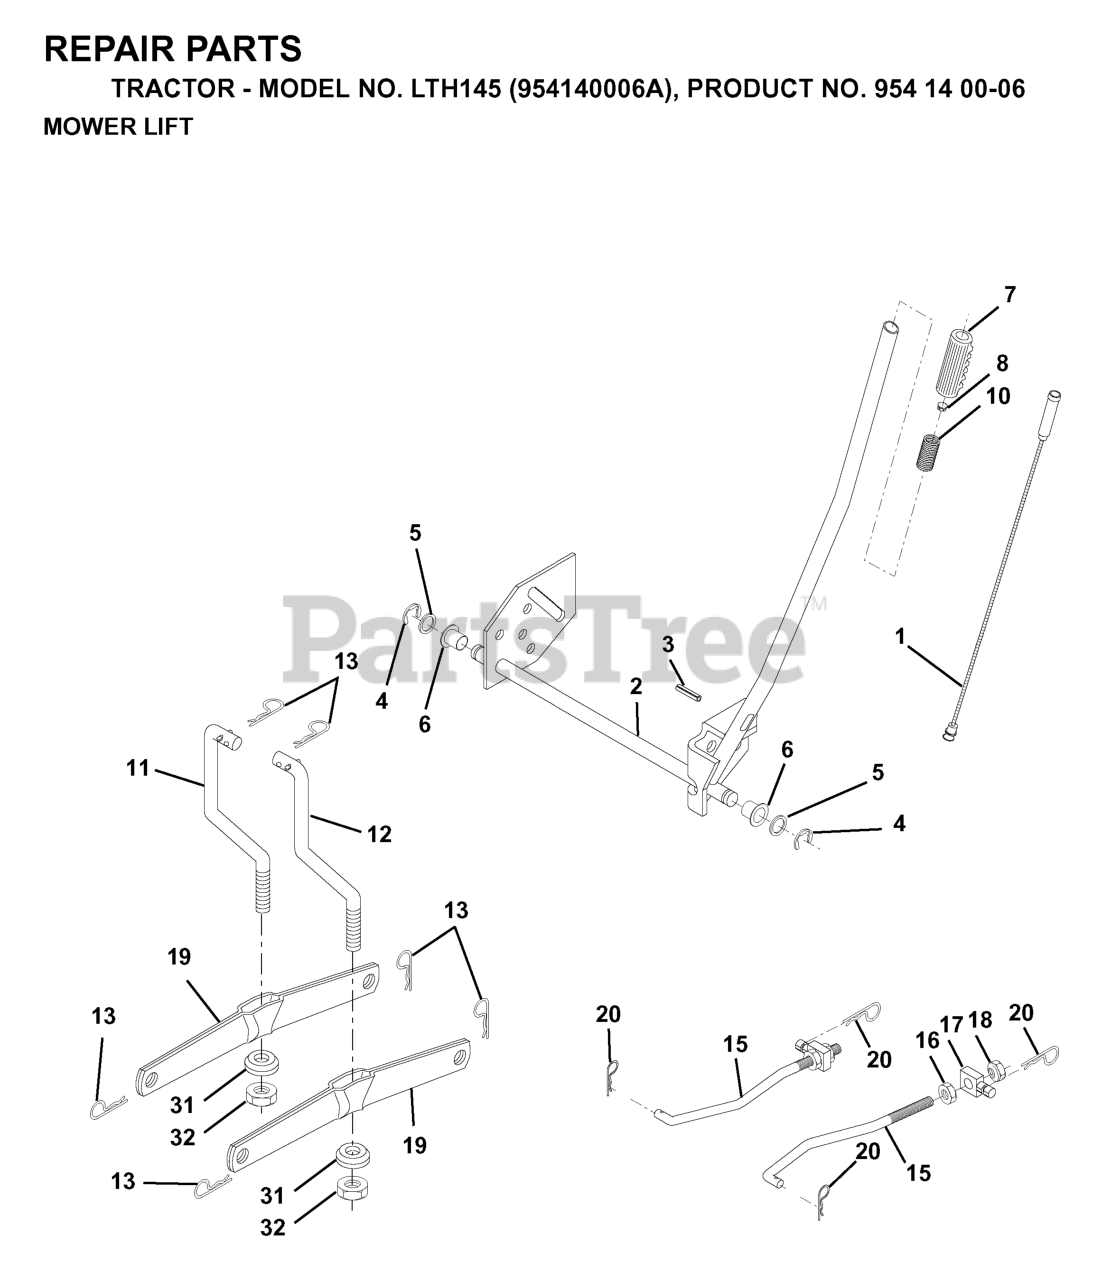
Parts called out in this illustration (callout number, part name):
1	WIRE.INNER.HANDLE.LIFT.LEVER
2	SHAFT ARM LIFT RH
3	PIN GROOVE.
4	RETAINING RING LT
6	BEARING.NYLON
8	PLUNGER BUT KIT
10	SPRING, COMP T
11	LINK LIFT LH
12	LINK LIFT RH
13	RETAINER-SPRNG RB
15	FRONT LINK
16	NUT.HEX.JAM.1/2-13
17	TRUNION
18	NUT.LK.W/WSH.1/2.
19	ARM.REAR.SUSPENSION
20	SPRING RETAINER
31	BEARING PIVOT
32	NUT CROWNLOCK 3/8-24
